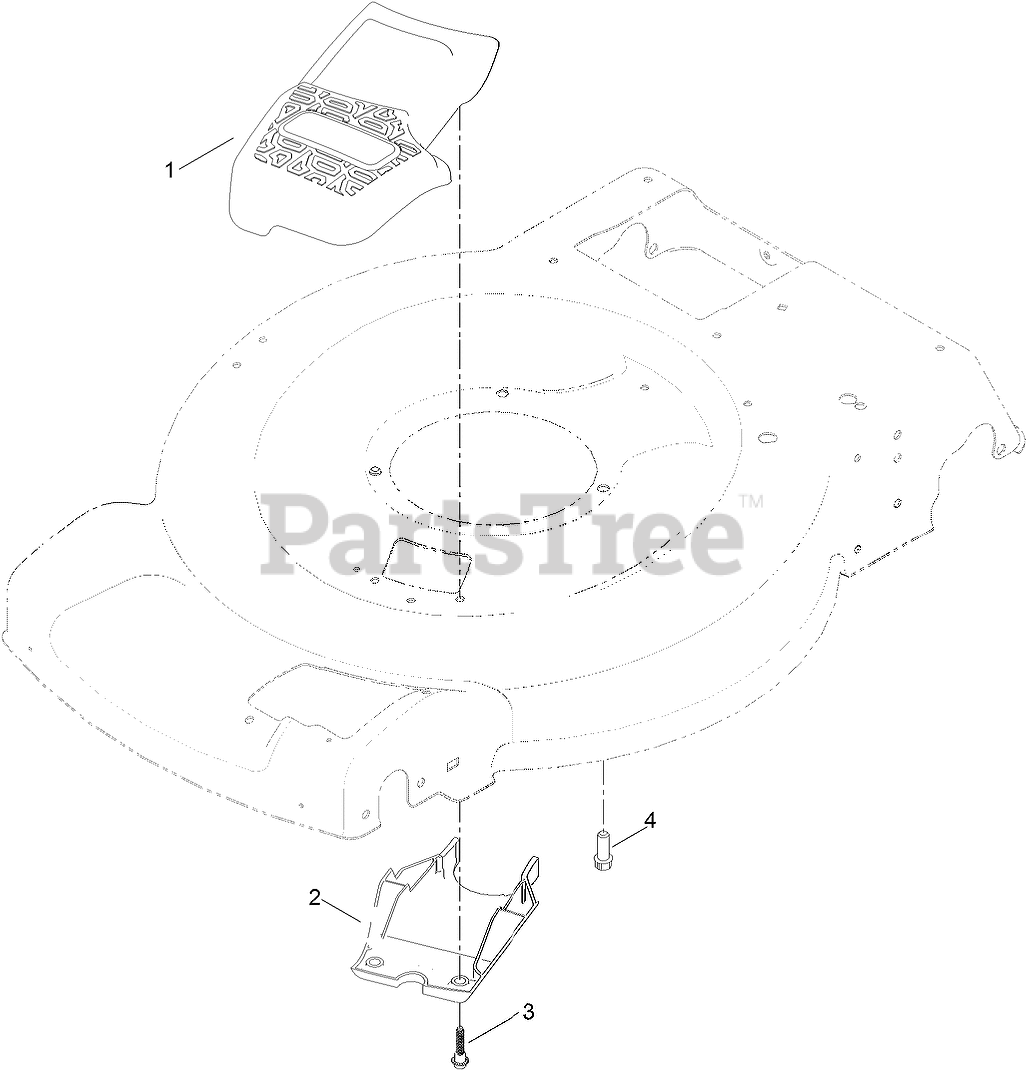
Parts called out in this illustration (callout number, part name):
1	COVER-BELT, FRONT
2	COVER-BELT, FRONT
3	SCREW-SHOULDER, HHF
4	SCREW-TAPTITE
